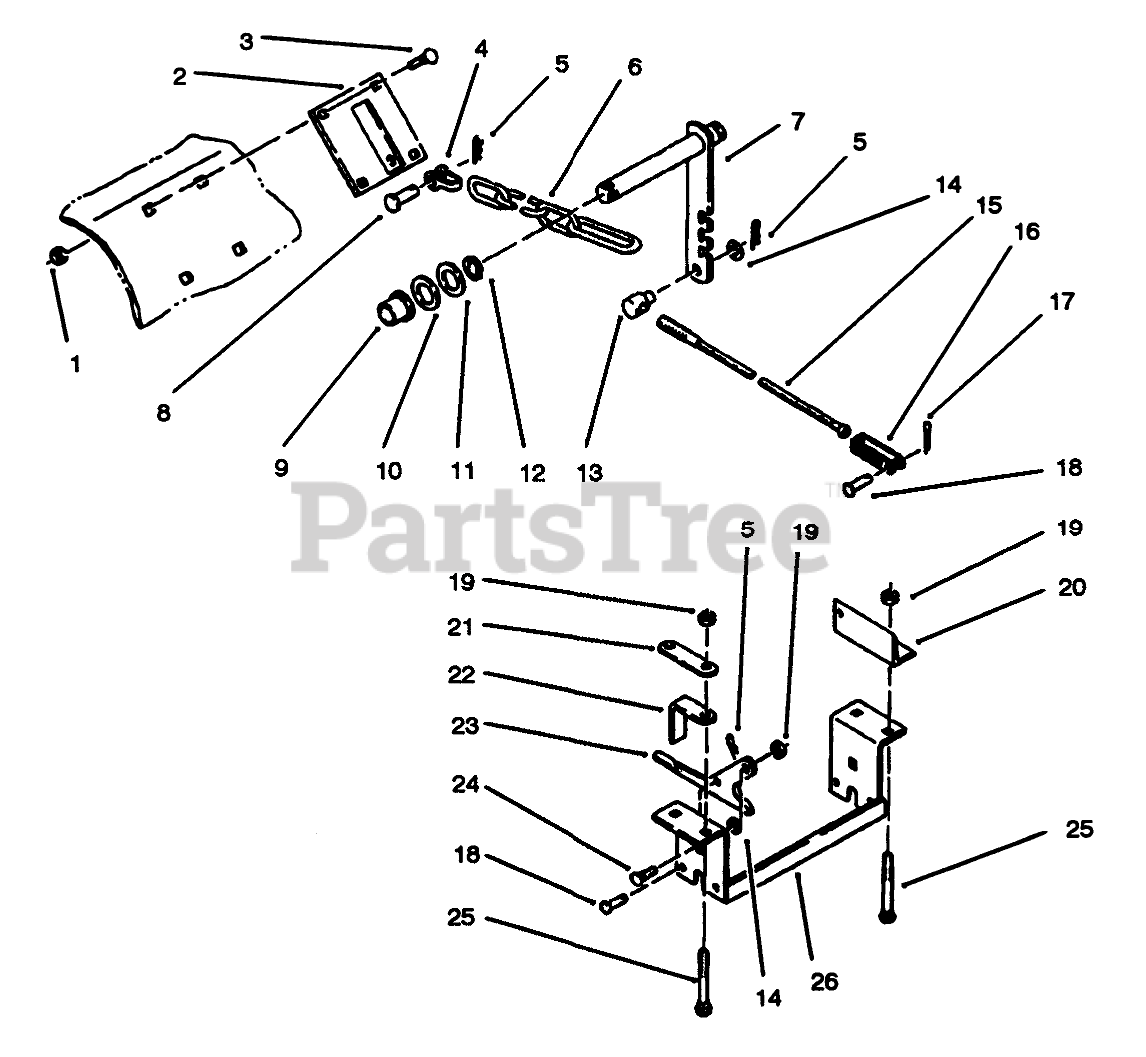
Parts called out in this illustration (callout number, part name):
1	NUT-LOCK, NI
2	Lift Plate
3	BOLT-CARR
4	CLEVIS ASM
5	Hairpin
6	CHAIN LIFT
7	ASSY LEVER R
8	Clevis Pin
9	BUSHING-BRONZE
10	WASHER
11	WASHER-SHIM
12	E-RING
13	TRUNNION-CLUTCH ROD
14	WASHER-FLAT
15	CABLE
16	CLEVIS-SHORT
17	Cotter Pin
18	Pin
19	NUT-HEX
20	LINK-BRACKET R
21	BRACKET-REAR LINK MOUNTING
22	SPACER-BRACKET
23	PLATE-LATCHING
24	Bolt-Carriage
25	SCREW-CARR
26	Bracket
